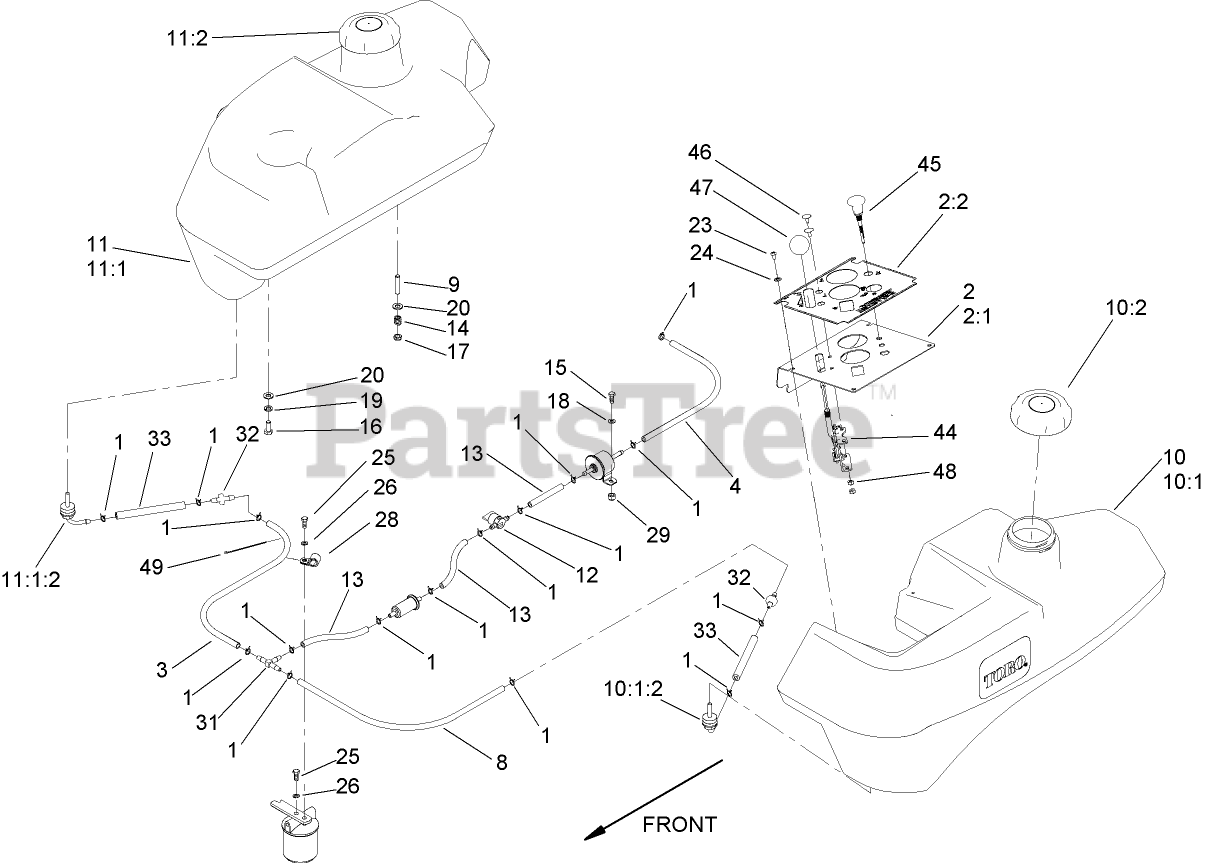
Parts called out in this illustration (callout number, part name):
2	CONTROL PANEL ASM
2:1	PANEL-CONTROL
2:2	DECAL-PANEL, CONTROL (LC)
3	HOSE-FUEL
4	HOSE-FUEL
8	HOSE-FUEL
10	LH FUEL TANK KIT
10:1	TANK-FUEL, LH
10:1:2	FITTING-FUEL, BULKHEAD
10:2	CAP-FUEL, GAS
11	RH FUEL TANK KIT
11:1	TANK-FUEL, RH
11:1:2	FITTING-FUEL, BULKHEAD
11:2	CAP-FUEL, GAS
12	VALVE-FUEL
13	HOSE-FUEL
14	SPRING-TANK, FUEL
15	SCREW-HH
16	SCREW-HH
17	NUT-LOCK, NI
18	WASHER-FLAT
19	WASHER-LOCK
20	WASHER-PLAIN
23	SCREW-PPH
24	WASHER-SPRING
25	SCREW-HH
26	WASHER-LOCK
28	CLIP-LOOM
29	NUT-HF
31	FITTING-TEE, BARBED
32	VALVE-CHECK, FUEL
33	HOSE-FUEL
44	CABLE-THROTTLE
45	CONTROL-CHOKE, PUSH / PULL
46	BOLT-CARR
47	KNOB-BALL
48	NUT-LOCK, NI
49	TIE-PLASTIC
